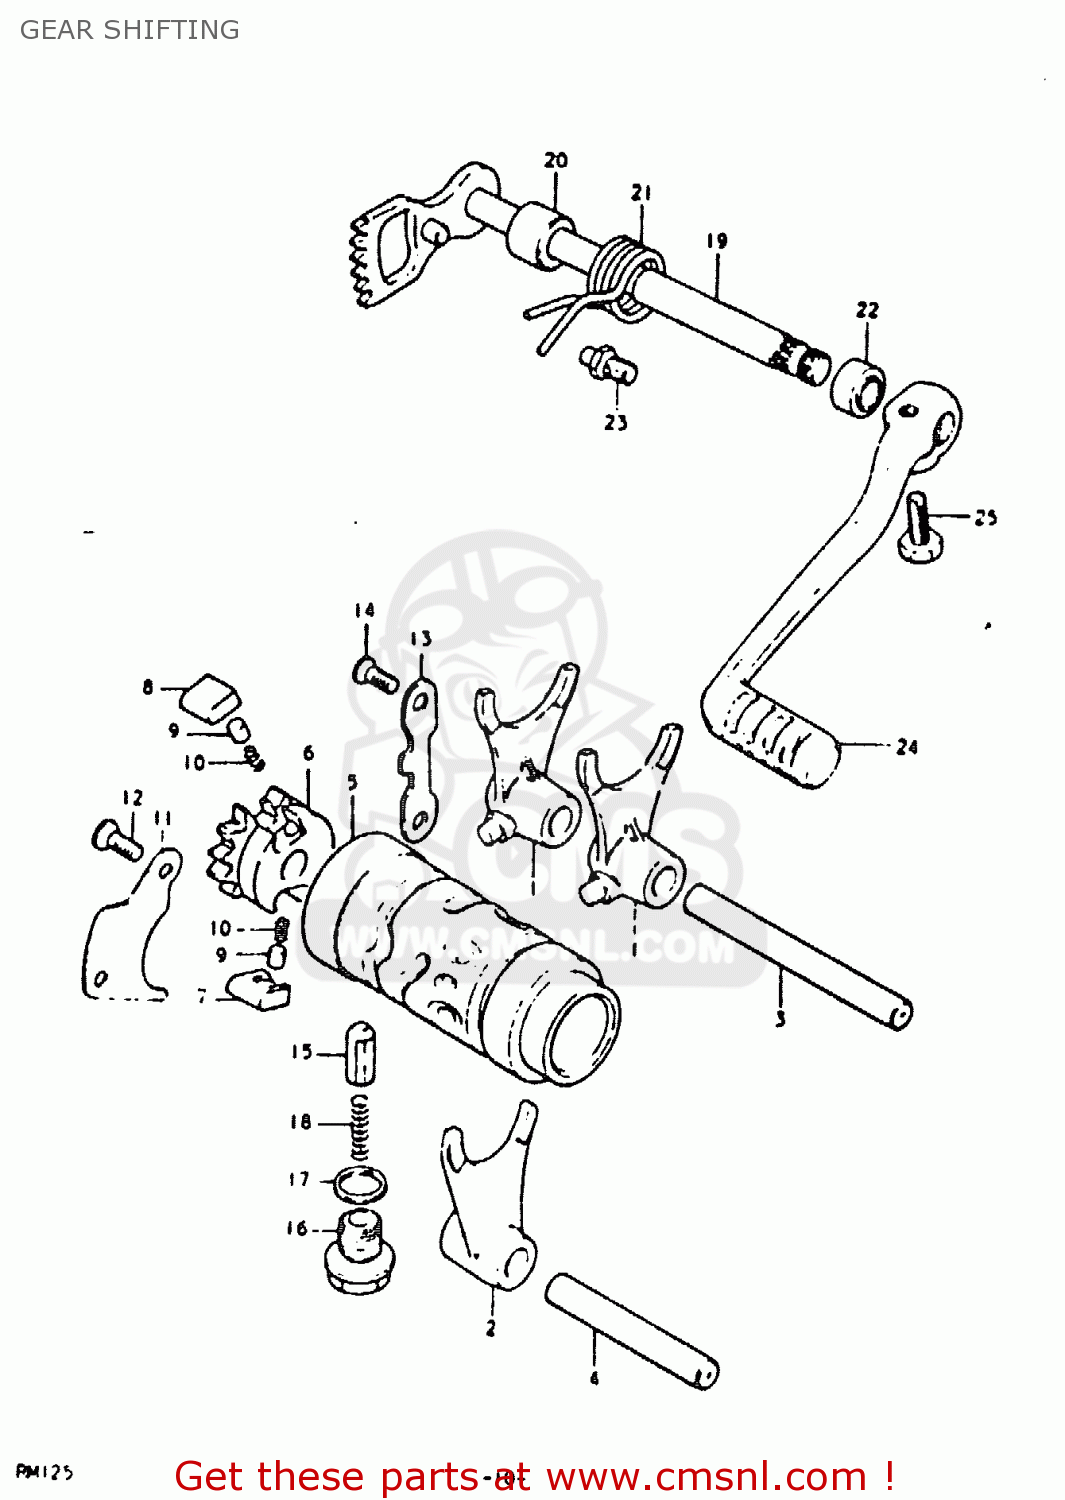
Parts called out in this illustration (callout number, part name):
1	FORK,GEAR SHIFT NO.1
2	FORK,GEAR SHIFT NO.2
3	SHAFT,GEAR SHIFT FORK
4	SHAFT,GEAR SHIFT FORK
5	CAM,GEAR SHIFT
6	RETAINER,GEAR SHIFT CAM
7	PAWL,GEAR SHIFT NO.1
8	PAWL,GEAR SHIFT NO.2
9	PIN(5X8)
10	SPRING
11	LIFTER,GEAR SHIFT PAWL
12	SCREW
13	GUIDE,GEAR SHIFT CAM
14	SCREW
15	STOPPER,GEAR SHIFTING
16	BOLT,GEAR SHAFT CAM STOPPER
17	GASKET(14X19.2X2) (NAS)
18	SPRING
19	SHAFT,GEAR SHIFT
20	SPACER(12X20X15.3)
21	SPRING
22	OIL SEAL
23	STOPPER,GEAR SHIFT CAM
24	LEVER ASSEMBLY,GEAR SHIFTING
25	BOLT
